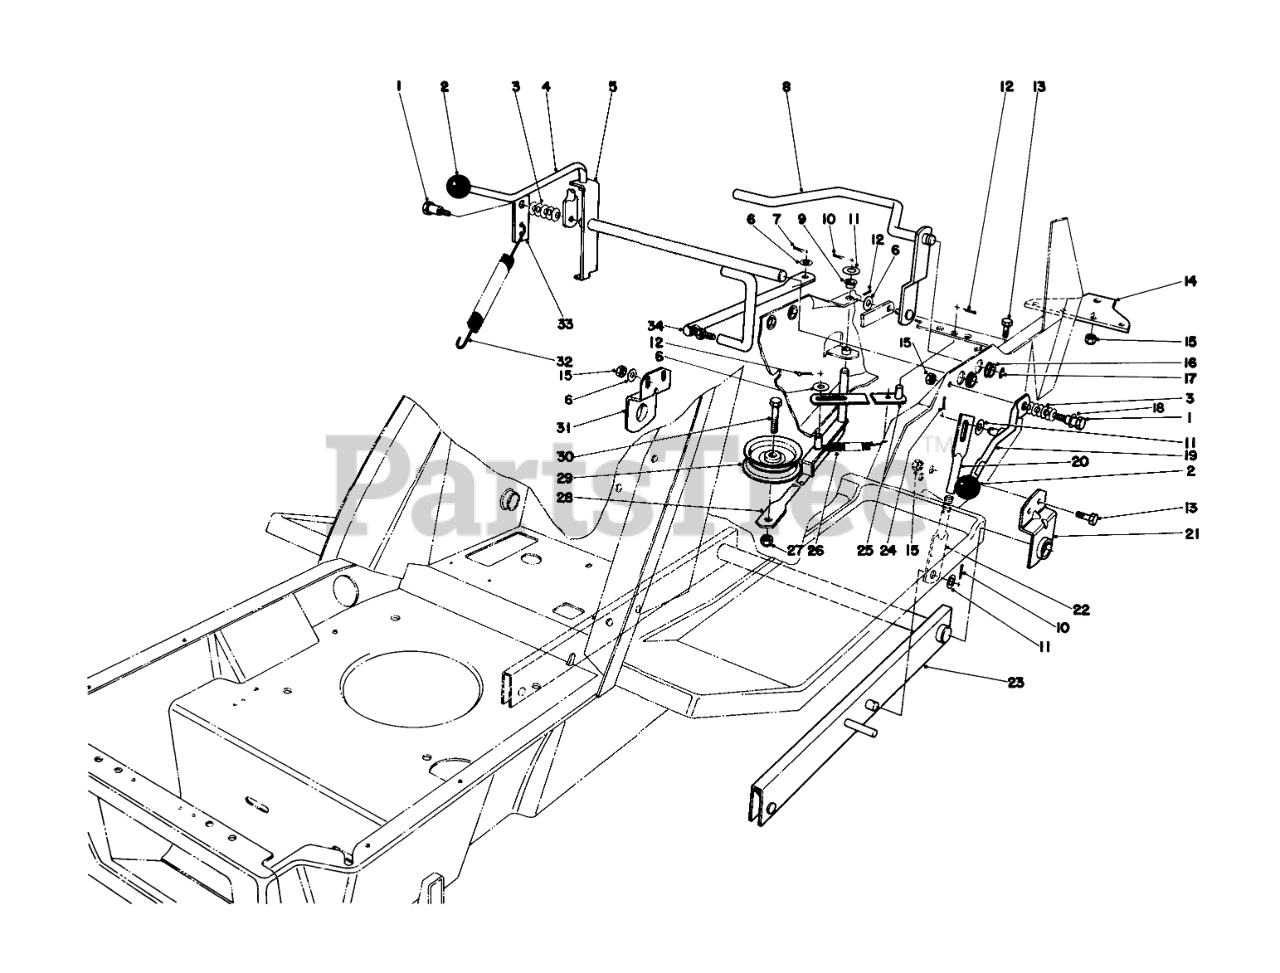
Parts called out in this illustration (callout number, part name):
1	BOLT-SHOULDER
3	WASHER-BELLEVILLE
4	SHIFT LEVER BO
5	Shim Lever
6	WASHER-PLAIN
7	PIN-COTTER
8	CLUTCH ACTUATOR WA B
9	BUSHING-NYLINER
10	PIN-COTTER
11	WASHER-FLAT
12	PIN-COTTER
13	SCREW-HH
14	HITCH PLATE R
15	NUT-LOCK, CONE
16	Nyliner
17	E-RING
18	WASHER-FLAT
19	HOC HANDLE WA B
20	Height of Cut Adjustment Tube
21	LH PIVOT BAR RET B
22	Strap Height of Cut
23	Bar-Pivot
24	PIN-COTTER
25	SPRING RET WA B
26	DECK TENSION SPRNG O
27	NUT-LOCK, CONE
28	IDLER ARM WA BO
29	IDLER PULLEY
30	SCREW-HH
31	RH PIVOT BAR RET B
32	TRACTION SPRING
33	BRKT-COBALANCE SPRING
34	SHIFT ARM BO
